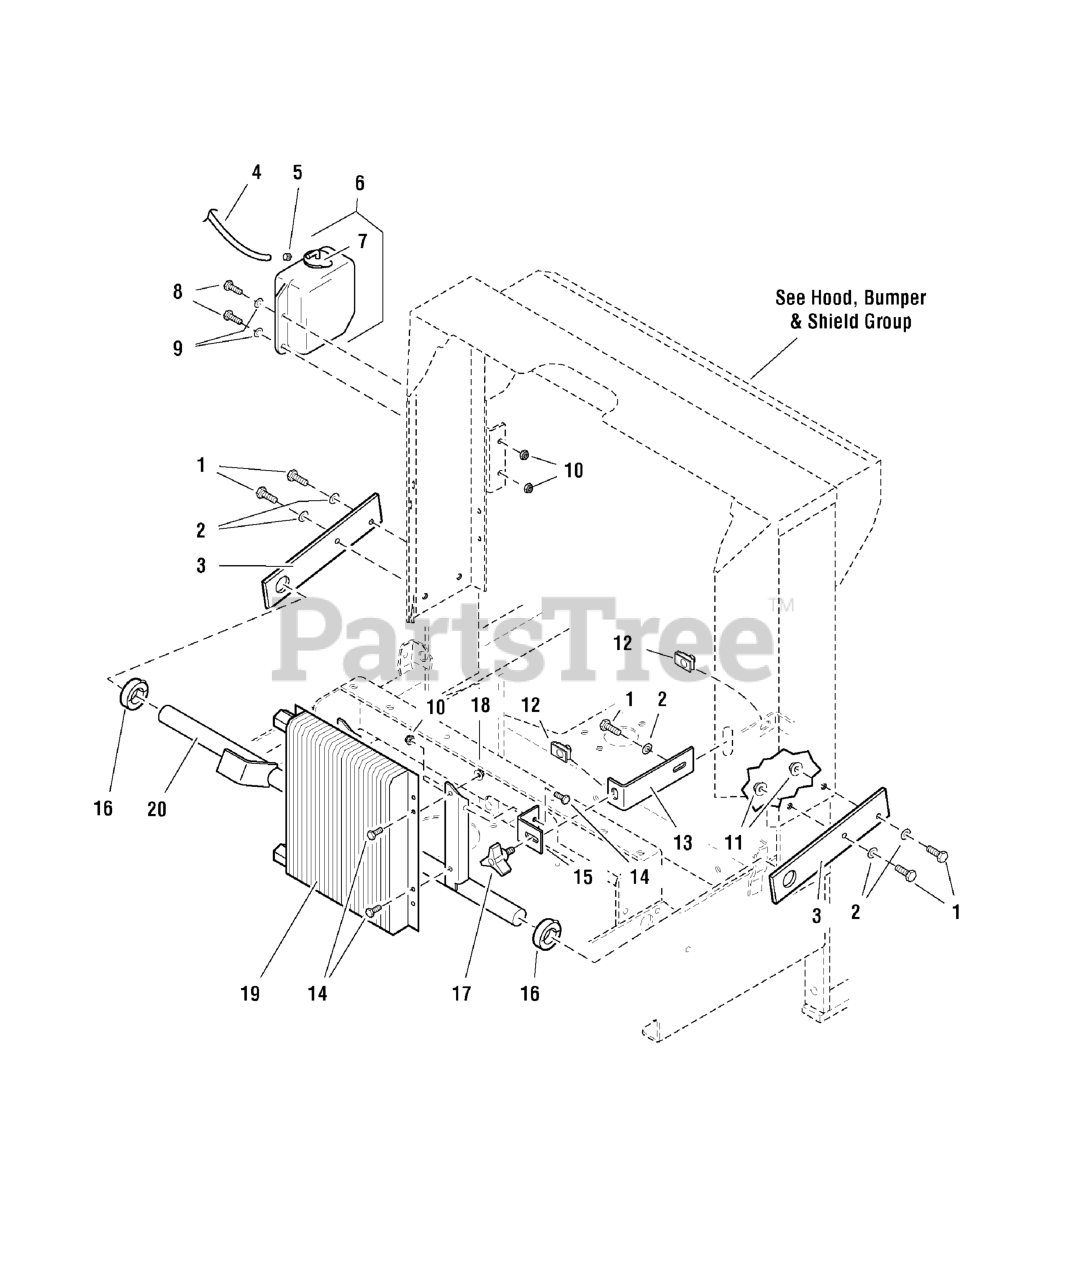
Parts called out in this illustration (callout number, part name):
1	BOLT, 5/16-18 X 1 GD5 YZ
2	WASHER, 5/16" SAE
3	OIL COOLER PIVOT PLATE
4	OVERFLOW HOSE
5	CLAMP, Hose
6	EXPANSION TANK, Complete
8	BOLT, 1/4-20 X 1" GD5 CZ
9	WASHER, 1/4 SAE
10	NUT, 1/4-20 HEX NYLON LOCK
11	NUT, 5/16-18 HEX SERRATED FLANGE (LARGE)
12	BODY CLIP, 5/16-18-7GA MATERIAL
13	COOLER PIVOT ANCHOR
14	SCREW, Allen Head, 1/4-20 x 1/2
15	COOLER LOCK BRACKET
16	COLLAR, 1" Split
17	KNOB
18	NUT, 1/4-20 HEX SERR. FLANGE
19	OIL COOLER
20	OIL COOLER MOUNT
